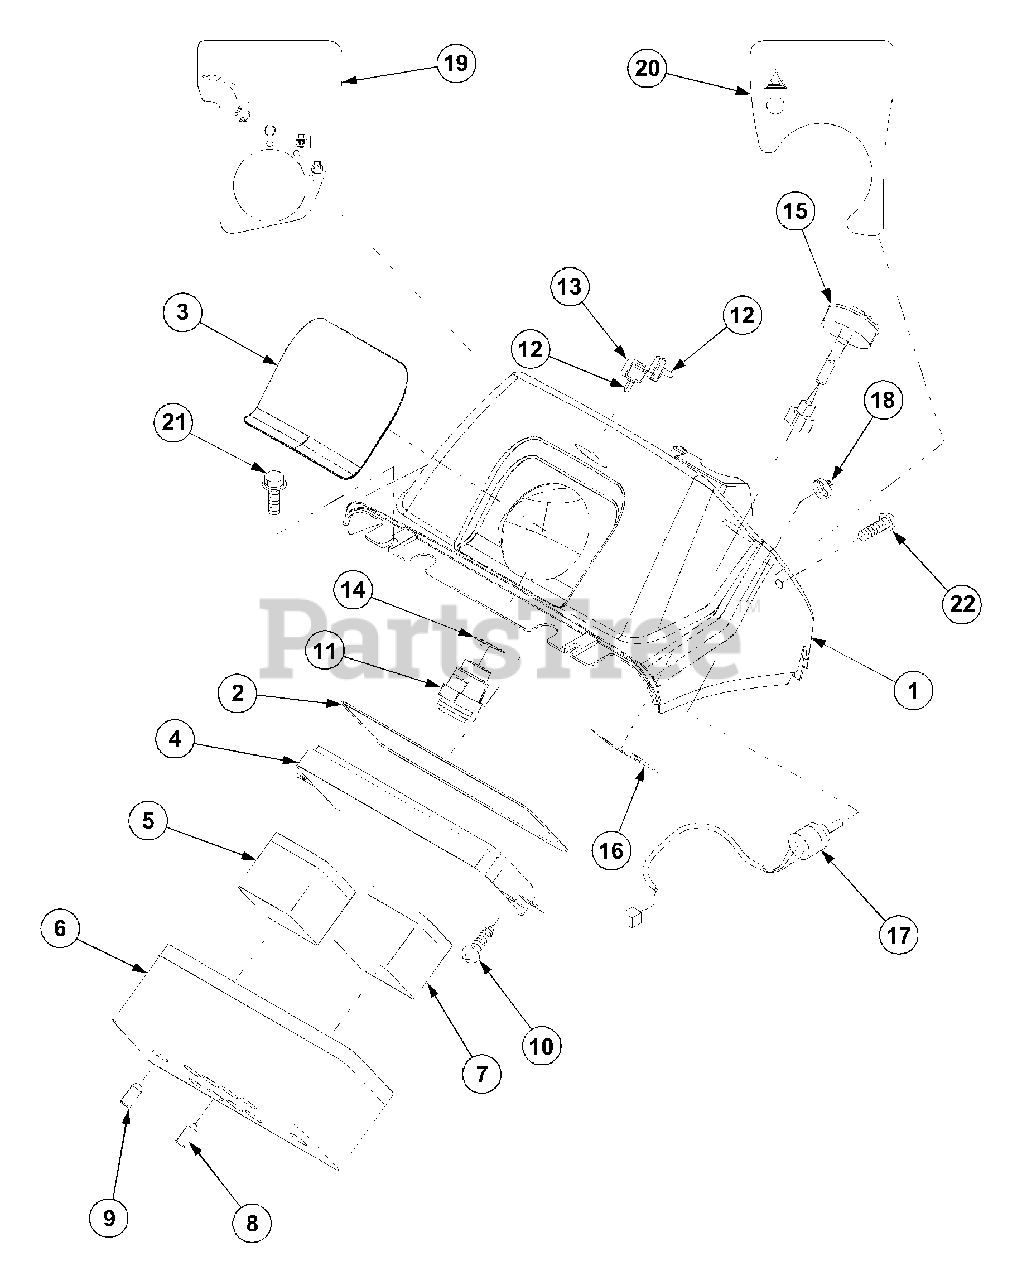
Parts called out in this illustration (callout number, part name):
7	Tacho Meter Ass'y
10	Screw,Tapping
11	Starter Switch
15	Switch,Combinat
21	Bolt,w/Washer
